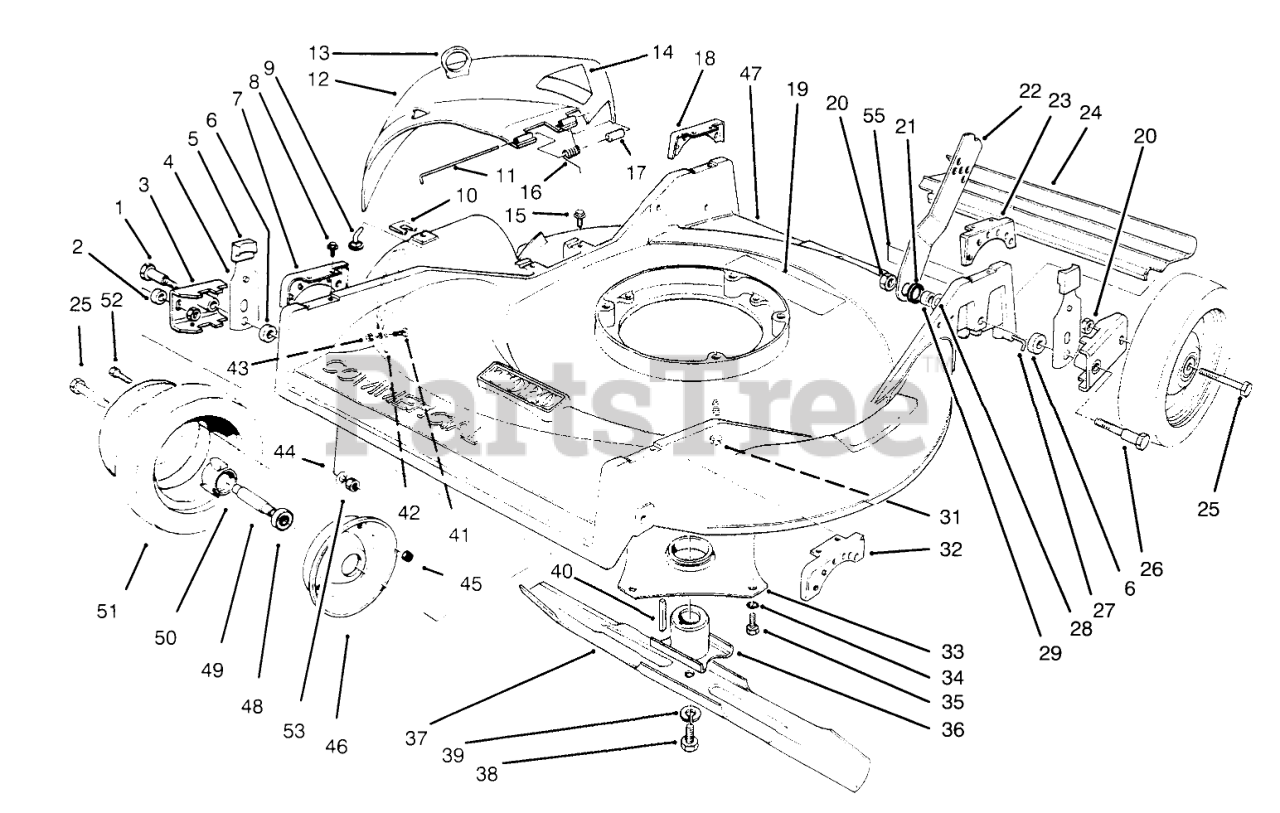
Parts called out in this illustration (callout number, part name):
1	PIVOT SCREW
2	SPACER-WHEEL
3	PIVOT ARM
4	SPRING ARM ASM-FRONT
5	KNOB-ARM
6	SPACER-PIVOT
7	FRT RIGHT QUAD
8	SCREW-HWHTF
9	BAG CHUTE PIN
10	BAG CHUTE CLIP PIN
11	DEFLECTOR HINGE PIN
12	Deflector (Incl. Ref. #14)
13	LIFT LOOP
14	DECAL-DANGER
15	SCREW-HWH
16	DEFLECTOR SPRING
17	SLEEVE
18	REAR RIGHT QUAD
19	DECAL-INSTRUCTION, SAFETY
20	NUT-LOCK, NI
21	HANDLE LATCH SPACER
22	Latch-Handle
23	REAR LEFT QUAD
24	SHIELD - TRAILING
25	SCREW-HH
26	REAR PIVOT SCREW
27	SHIELD ROD
28	WASHER-BELLEVILLE
29	HANDLE LATCH SPACER
31	Screw-Flange Head
32	FRT LEFT QUAD
33	CRNKSHFT PROTECT ASM
34	WASHER-LOCK, INTERNAL
35	SCREW-HWHTF
36	RETAINER-BLADE
37	Blade
38	SCREW-HH
39	WASHER-LOCK
40	KEY-SQUARE
41	SCREW-CARR
42	Bar-Safety
43	NUT-LOCK, NI
44	WASHER-BELLEVILLE
45	NUT-LOCK, NI
46	Wheel-Half
47	Housing (Incl. Ref. #19, 54 & 55)
48	BEARING-WHEEL
49	SPACER-BEARING
50	HUB-BEARING
52	SCREW-HH
53	NUT-LOCK, CONE
55	DECAL-WARNING
